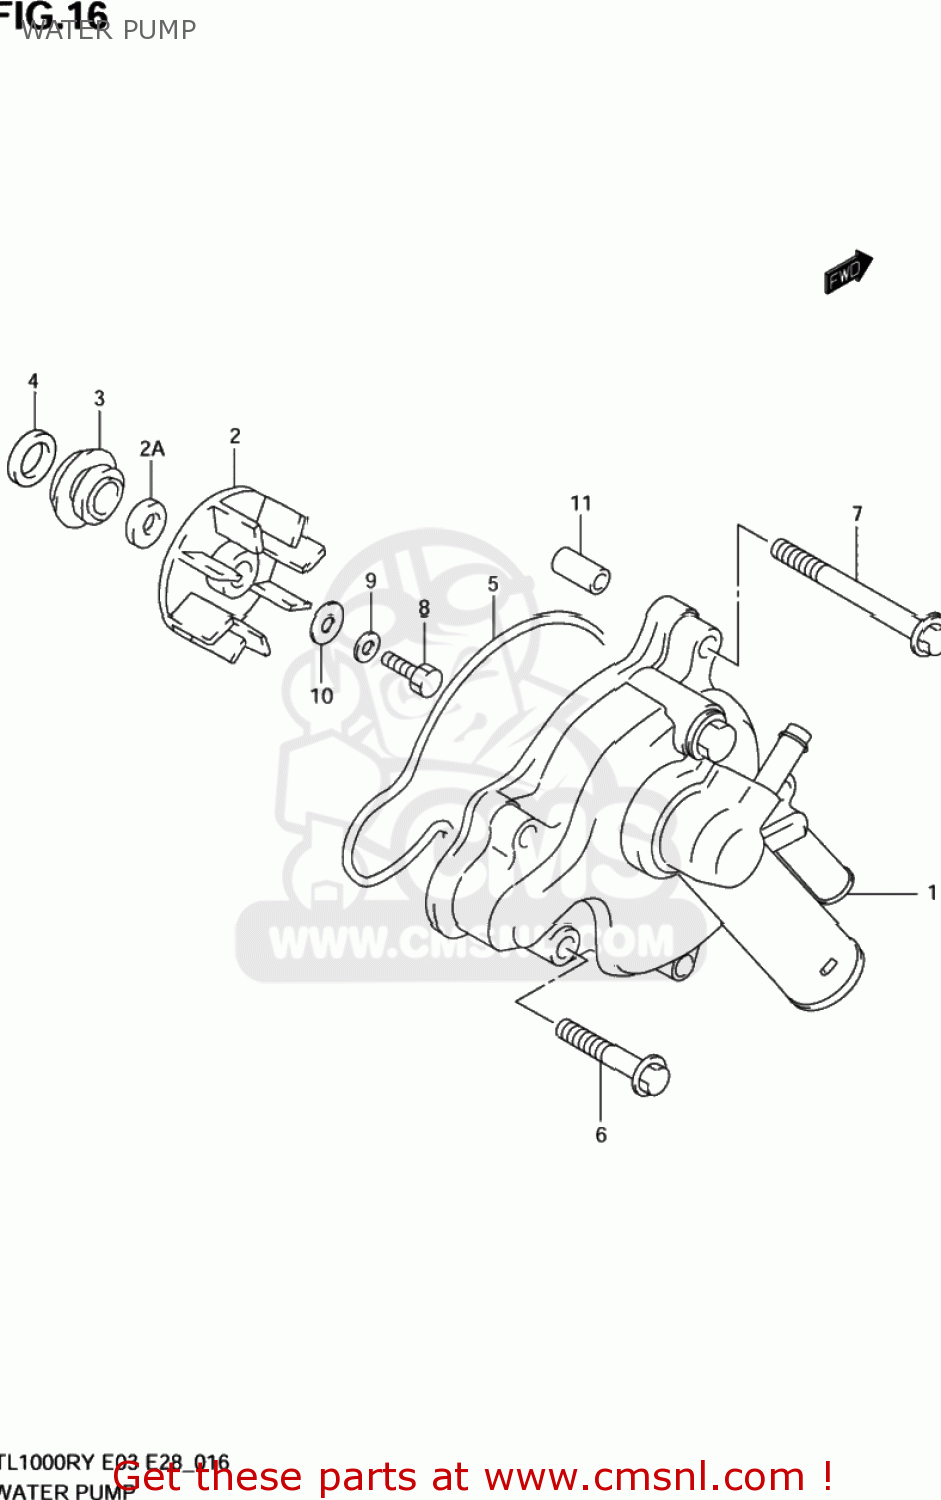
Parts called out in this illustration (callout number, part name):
1	CASE,WATER PUMP
2	IMPELLER,WATER PUMP
2A	WASHER,IMPELLER
3	SEAL,MECHANICAL
4	SEAL,WATER PUMP SHAFT OIL
5	O RING,WATER PUMP CASE
6	BOLT
7	BOLT
8	BOLT(6X13)
9	WASHER
10	GASKET(6X15X2.2) (NAS)
11	PIN
